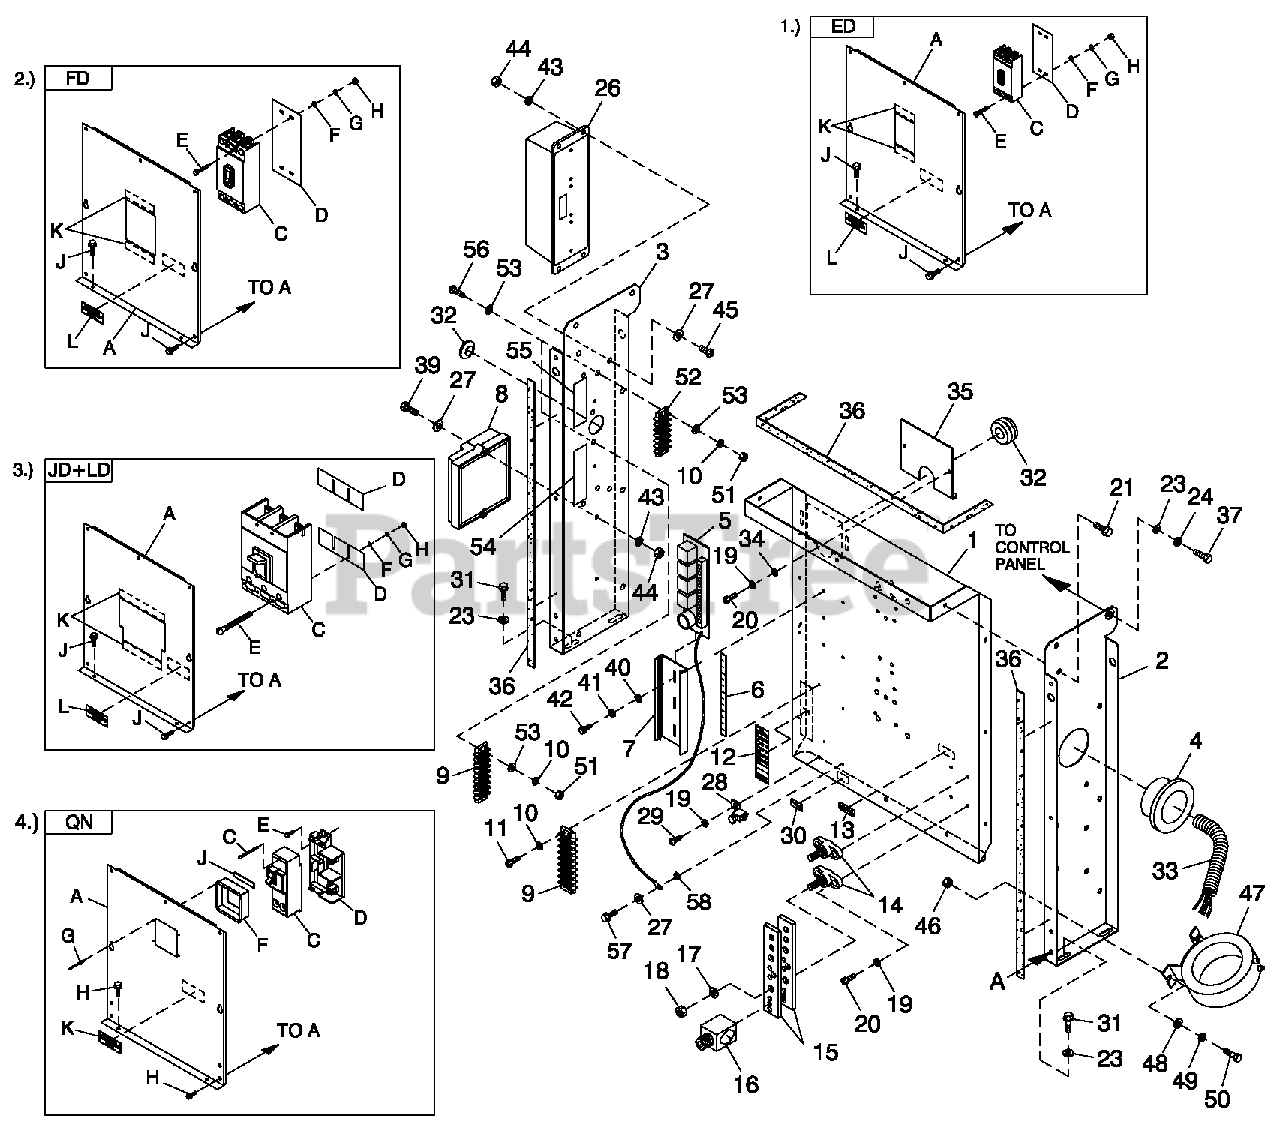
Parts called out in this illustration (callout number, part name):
1	PAN CB CONN BOX
1	UL CIRCUIT BREAKER (ED)
2	STAND RH CONTROL
2	UL CIRCUIT BREAKER (FD)
3	STAND LH CONTROL HPNL
3	UL CIRCUIT BREAKER (JD+LD)
4	BUSHING SNAP SB-2.5-31
4	UL CIRCUIT BREAKER (QN)
5	ASSY RELAY PCB12VDC
6	DECAL SPARE OUTPUT
7	RAIL SNAPTRACK PCB HOLDER BULK
8	ASSY PCB IGNITION MODULE 2.4L
9	BLOCK TERM 20A 8 X 6 X 1100V
10	WASHER LOCK #6
11	SCREW PHTT #6-32X1/2 ZYC
12	DECAL CPL CUST CONN H CTRL
13	DECAL NEUTRAL
14	JUNCTION BLOCK 3/8-16
15	BUS BAR NEUTRAL BLOCK 390
16	LUG SLDLSS 600/250-1/0 X 1/4-28
17	WASHER LOCK 3/8
18	NUT HEX 3/8-16 STEEL
19	WASHER LOCK M5
20	SCREW PHTT M5-0.8X 16 ZYC
21	SCREW THFM6-1X16NWA Z/JS
23	WASHER FLAT 1/4-M6 ZINC
24	WASHER LOCK M6-1/4
26	INTERFACE 3PH 416/480V
27	WASHER FLAT #10 ZINC
28	LUG SLDLSS #6-14X 13/64 CU
29	SCREW HHTT #10-32X3/8 CZ
30	DECAL GROUND LUG
31	SCREW HHTT M6-1.0 X 16ZYC
32	GROMMET 1.25 X .25 X .75
33	CONDUIT FLEX 2.0" ID (36" LG)
34	WASHER FLAT M5
35	PLATE WIRE SNGLGALV
36	TAPE ELEC 1/2 FOAM (AS REQ'D)
37	SCREW HHC M6-1.0X 16 G8.8
39	SCREW PPHM #10/32X2
40	WASHER FLAT M4
41	WASHER LOCK #8-M4
42	SCREW PHTT M4-0.7X 10 ZYC
43	WASHER LOCK #10
44	NUT HEX #10-32 STEEL
45	SCREW PRHM #10-32X1/2
46	NUT HEX M6 X 1.0 G8 YEL CHR
47	XFMRCURRENT 200AW/BRKT (120/240 1P)
48	WASHER FLAT 1/4-M6 ZINC
49	WASHER LOCK M6-1/4
50	SCREW HHC M6-1.0X16G8.8
51	NUT HEX #6-32 STEEL
52	BLOCK TERM 20A 6 X 6 X 1100V
53	WASHER FLAT #6 ZINC
54	DECAL H-100 IFT
55	DECAL EXCITER
56	SCREW RHM #6-32 X 3/4
57	SCREW HHTT M4-0.7 X 8ZP
58	WASHER SHAKEPROOF EXT #10 STL
A	COVER ED CB SHORT STND
C	CB 0050A 3P 480V S ED4 LL
D	INSULATOR CBS(ED-3P)
E	SCREW RHM #10-32X4-1/2
F	WASHER FLAT #10 ZINC
G	WASHER LOCK #10
H	NUT HEX #10-32 STEEL
J	SCREW THF M6-1 X 16 N WA Z/JS
K	TAPE ELEC 1/2 FOAM (AS REQ'D)
L	DECAL CUSTOMER CONNECT INSIDE
A	COVER CB CONN BOX
C	CB0150A 3P 600V SFD6 LL
D	INSULATOR CB FD FRAME 30MIL
E	SCREW SHC 1/4-20 X 4.5 G8.8 NZ
F	WASHER FLAT 1/4-M6 ZINC
G	WASHER LOCK M6-1/4
H	NUT HEX 1/4-20 STEEL
A	COVER JD/LD CB SHRT STAND
C	CB 0300A 3P 600V S JD6 LL
D	INSULATOR CIRCUIT BR. JD/LD
E	SCREW RHM 1/4-20X3
A	COVER QN FRM CB
C	CB 0150A 2P 240V S QN2 LL
D	BASE, QN CIRCUIT BREAKER
E	SCREW HHTT M5-0.8X 10 BP
F	COVER QN CB DISH
G	RIVET POP .125 X .275 SS
H	SCREW THF M6-1X16 N WA Z/JS
J	TAPE ELEC 1/2 FOAM (AS REQ'D)
K	DECAL CUSTOMER CONNECT INSIDE
